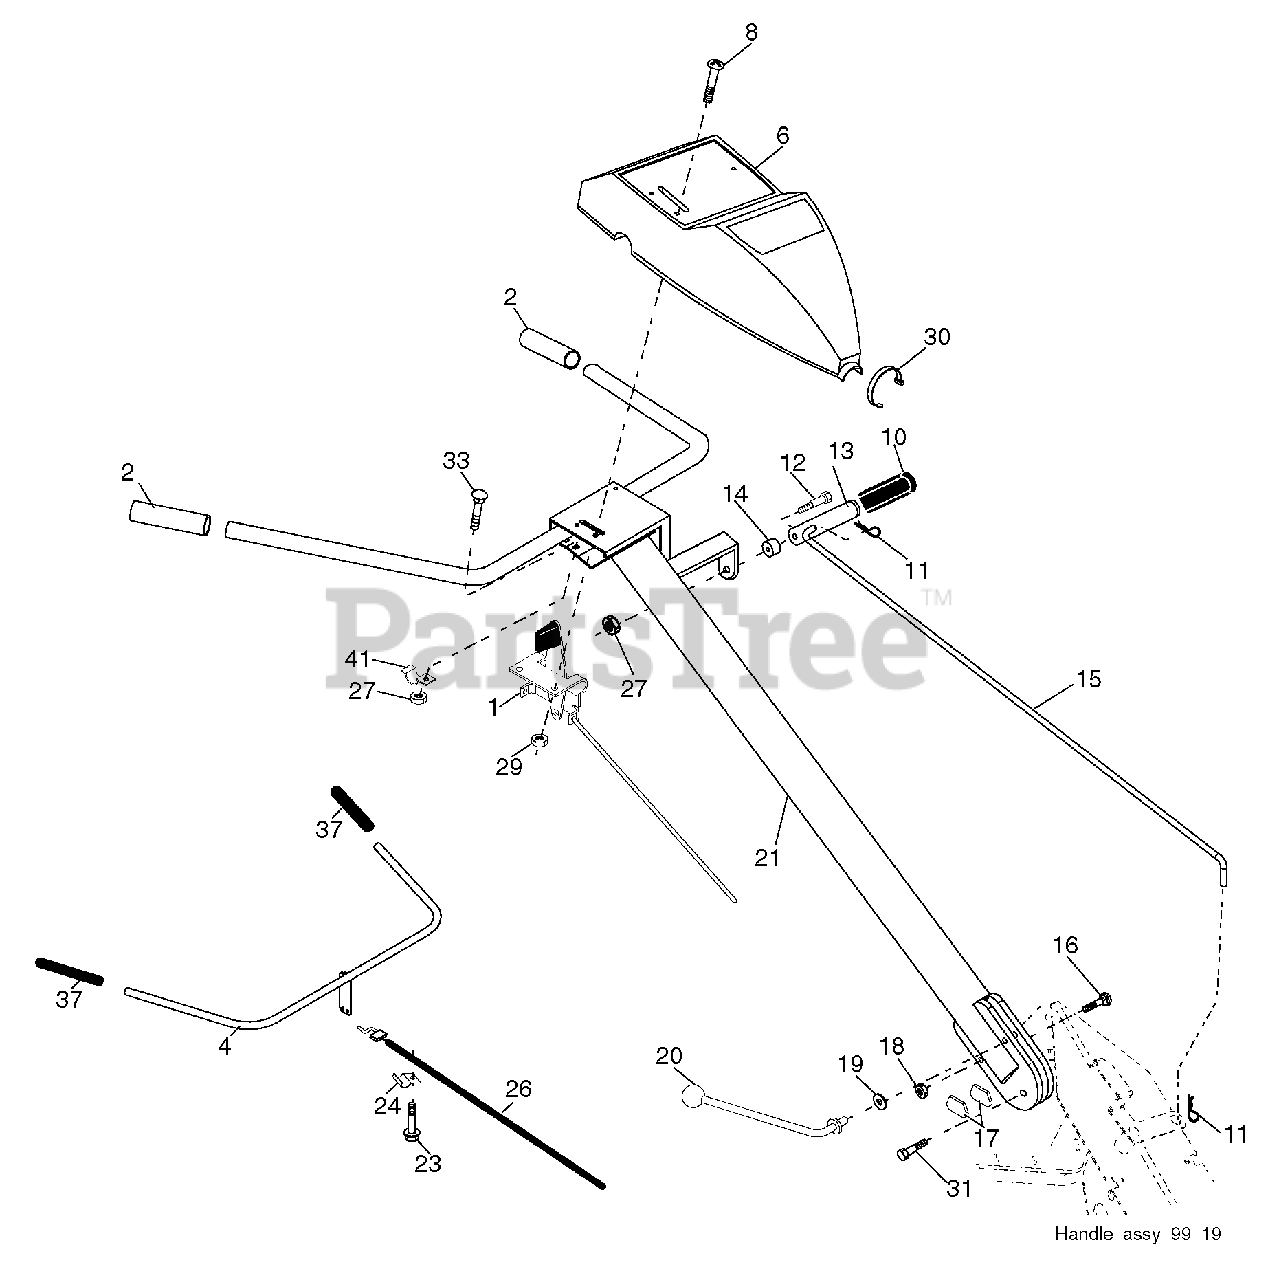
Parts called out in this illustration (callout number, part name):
1	Control, Throttle
2	Grip, Handle
4	Bar Assembly, Control
6	Panel, Control
8	Screw, Phd. #10-24
10	Grip, Handle
11	Clip, Hairpin
12	Bolt, Shoulder
13	Handle, Shift
14	Grommet, Rubber
15	Rod, Shift
16	Bolt, Carriage 3/8-16 x 1 Gr. 5
17	Lock, Handle
18	Nut, Crownlock 3/8-16 unc
19	Washer 13/32 x 1 x 11 Ga.
20	Lever, Lock, Handle
23	Screw, Hex Washer Hd. Slotted #10-24 x 1/2
24	Clip
26	Cable, Clutch
27	Nut Hex Flange 1/4-20 unc
29	Nut, Keps #10-24 unc
30	Tie, Cable
31	Bolt, Pivot
33	Bolt, Carriage 1/4-20 unc x 1/2
37	Grip, Bar, Control
41	Clamp, Bar, Control
